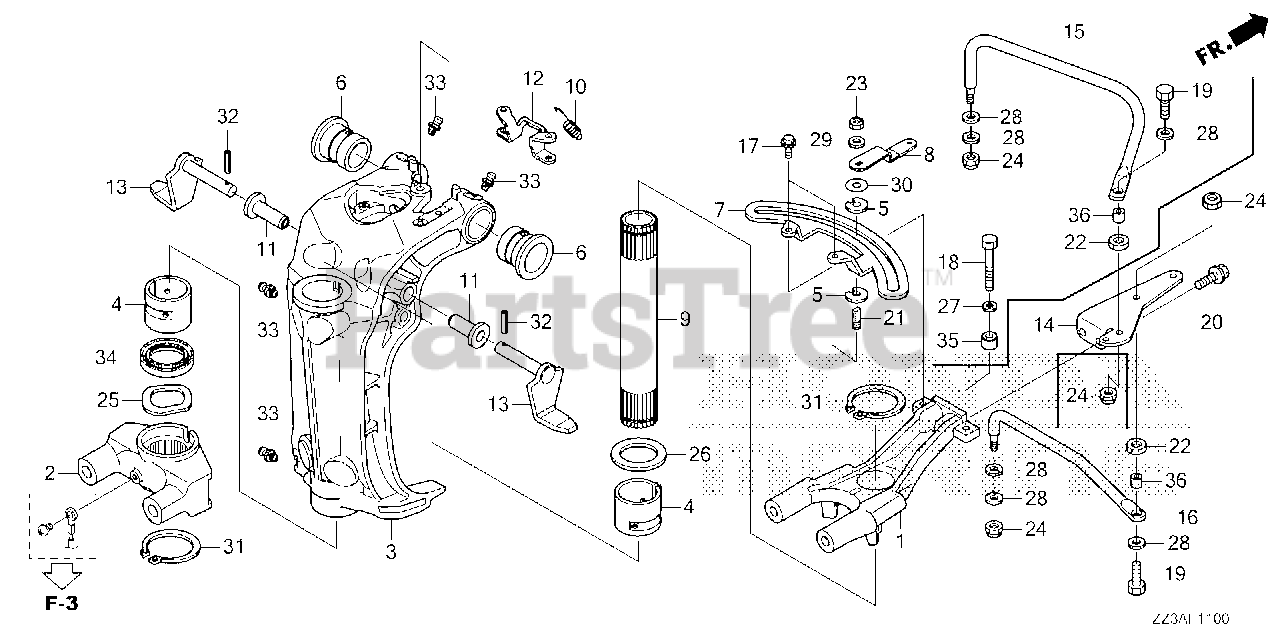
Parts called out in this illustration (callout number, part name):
1	FRAME, MOUNT
2	HOUSING, CENTER MOUNTING (LOWER) *NHB14M* (AQUA MARINE SILVER METALLIC)
3	CASE, SWIVEL *NHB14M* (AQUA MARINE SILVER METALLIC)
4	LINER, SWIVEL CASE
6	BUSH, SWIVEL CASE
9	SHAFT, SWIVEL
10	SPRING, TILT LEVER
11	BUSH, TILT ARM
12	BRACKET, TILTING
13	STOPPER, TILT
14	PLATE, STEERING
15	ROD, STEERING
16	ROD, STEERING
18	BOLT, HEX. (6X35)
19	BOLT (3/8-24UNF)
20	BOLT, FLANGE (10X25)
22	NUT (3/8-24UNF)
24	NUT, SELF-LOCK (3/8-24UNF)
25	WASHER, WAVE (40MM)
26	WASHER, THRUST (34MM)
27	WASHER, PLAIN (6MM)
28	WASHER (10MM)
31	CIRCLIP (OUTER) (39MM)
32	PIN, SPRING (2.5X20)
33	NIPPLE, GREASE
34	OIL SEAL (39.5X52X6) (ARAI)
35	COLLAR, DISTANCE (6.5X16X14.5)
36	COLLAR, STEERING ROD
